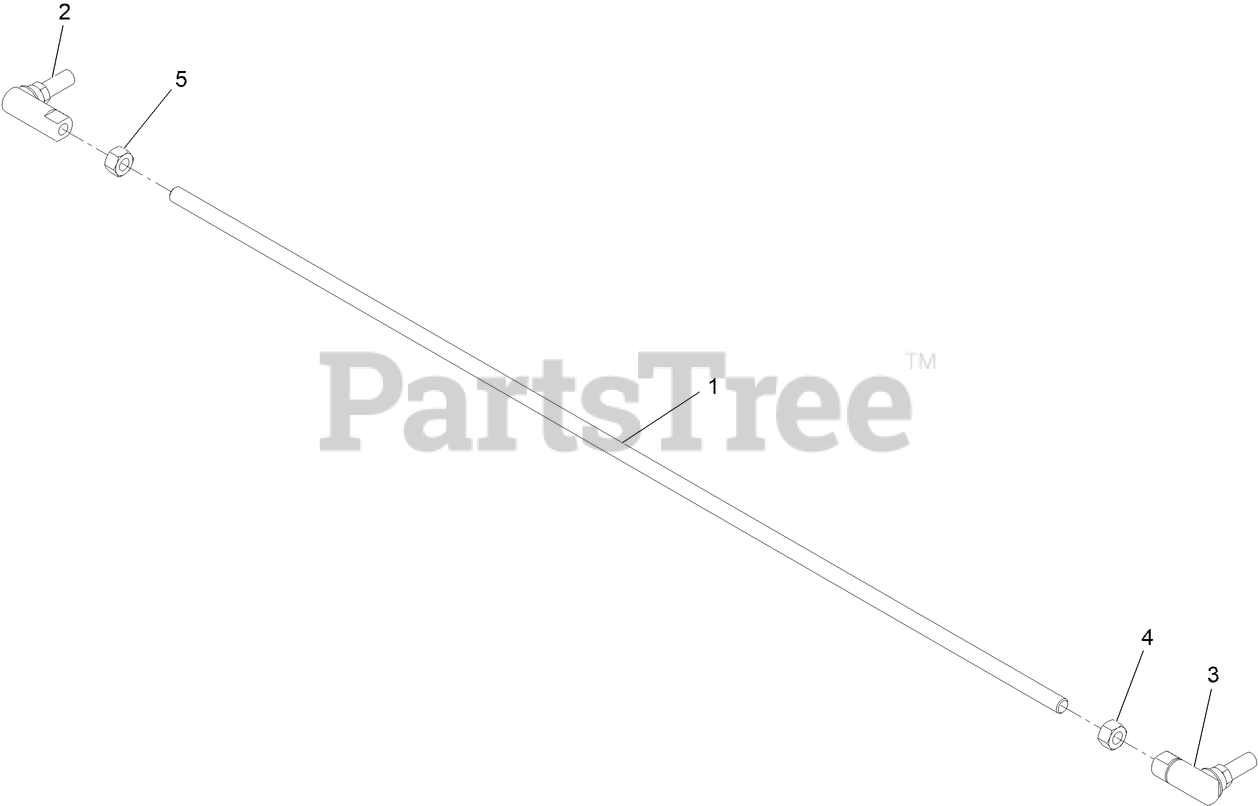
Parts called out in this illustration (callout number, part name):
1	ROD-BRAKE, LINKAGE
2	BALL JOINT-SS
3	BALL JOINT-SS
4	NUT-HEX, LH
5	NUT-HEX
